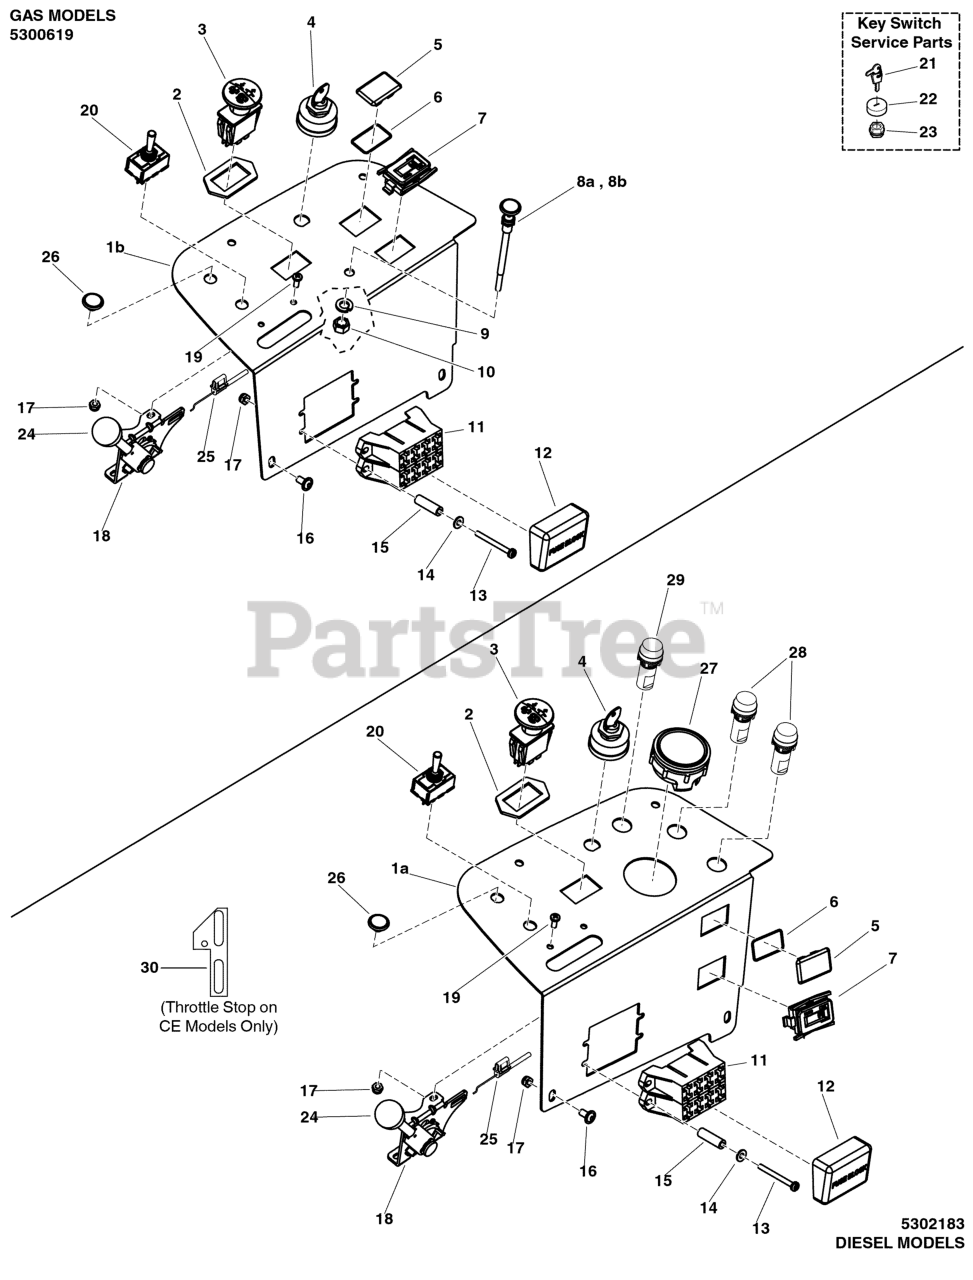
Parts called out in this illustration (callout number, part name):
2	RING, SWITCH RETAINER
3	SWITCH, BLADE ENGAGEMENT
4	SWITCH, IGNITION, 25 AMP, 6 PO
5	PLUG, .820X1.44 HOLE, BLACK PLASTIC
6	O-RING, 7/8 ID X 1/16 W
9	WASHER, 3/8 SPLIT LOCK
10	NUT, 3/8-24 HEX
11	FUSE BLOCK
12	COVER, DOUBLE FUSE BLOCK
13	SCREW, #10-24 X 2 ROUND PHILLIPS
14	WASHER, #10 SAE
15	SPACER, .20 X .38 X 1.25
16	SCREW, 1/4-20 X 1/2 ALLEN BH
17	NUT, #10-24 HEX NYLON LOCK
18	LEVER, THROTTLE CONTROL, HEAVY-DUTY
19	SCREW- #10-24 X 1/2 ROUND PHILLIPS
20	SWITCH, ACTUATOR
21	KEY, IGNITION MOLDED SET
22	COVER, PLASTIC, SNAP ON
23	PLASTIC NUT
24	THROTTLE CONTROL HANDLE/KNOB
26	PLUG, 1/2, BPF - 1/2
27	GAUGE, WATER TEMPERATURE
28	INDICATOR LAMP, RED LED
29	YELLOW LED PILOT LIGHT
30	PLATE, THROTTLE STOP
